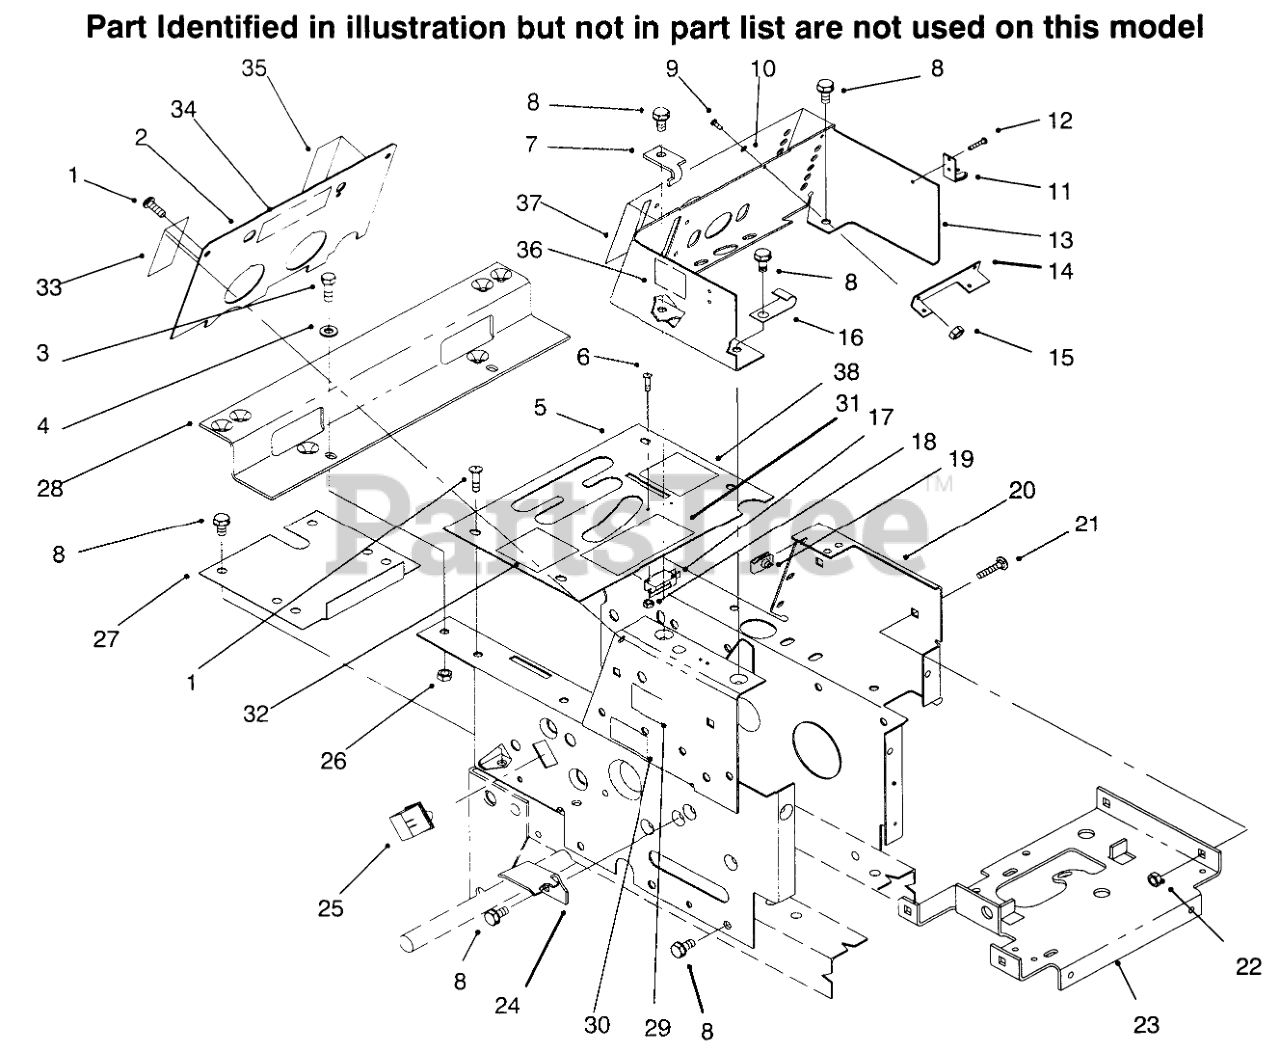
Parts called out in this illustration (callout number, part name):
1	SCREW-PPH
2	Plate-Hoodstand
3	SCREW-HH
4	WASHER-PLAIN
5	Plate-Shift Cover
6	Screw
7	STOP-PTO
8	Bolt
9	SCREW-PAN
10	Washer-Lock
11	KEEPER-LATCH
12	POPRIVET 1/8X 1/8 BK
13	Console
14	BRACKET
15	Nut
16	J-CLIP
17	SWITCH
18	NUT-HEX
20	Hoodstand
21	BOLT CARR. 5/16X1/2 BK
22	Nut
23	SUPORT-BATERYB
24	Bracket-Belt
25	SWITCH INTERLOCK
26	NUT-LOCK, NI
27	Cover-Dust
28	BRACKET-FENDER B
30	DECAL - MODEL 314-8
31	DECAL-DANGER
32	DECAL-SHIFT PATTERN
33	DECAL PTO CLUTCH
34	DECAL-BACK PLATE
35	DECAL-LIFT
36	DECAL ELECT SYSTEM
37	DECAL-LOWER DASH
38	DECAL-PARKING, BRAKE
